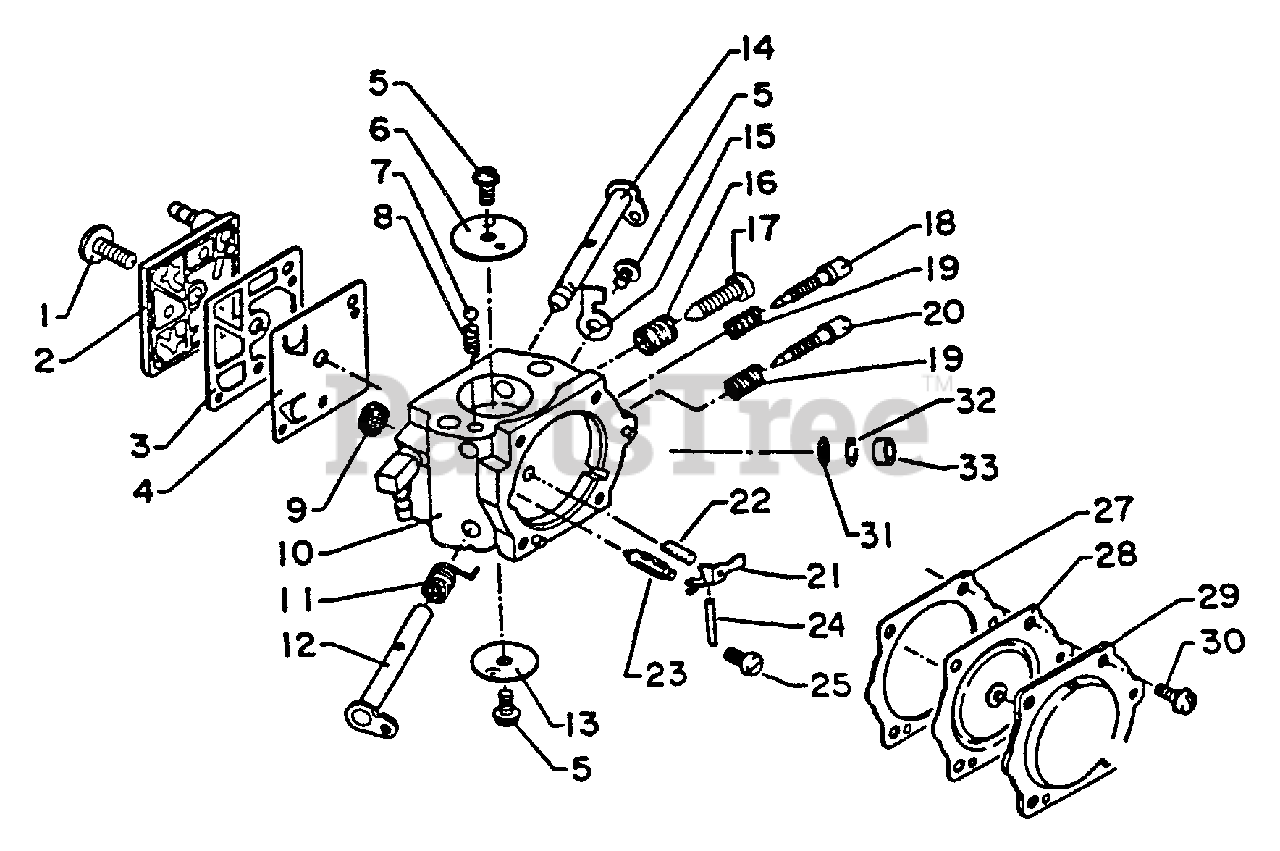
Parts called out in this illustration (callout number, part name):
1	SCREW, PUMP COVER
2	COVER, PUMP
3	GASKET, PUMP
4	DIAPHRAGM, PUMP
6	VALVE, THROTTLE
7	BALL, CHOKE
9	STRAINER
10	BODY, CARBURETOR
11	SPRING, THROTTLE RETURN
12	SHAFT, THROTTLE
13	VALVE, THROTTLE
14	SHAFT, CHOKE
15	STOP, THROTTLE
16	SPRING, IDLE ADJUST
17	SCREW, IDLE ADJUST
18	NEEDLE - LOW SPEED
19	SPRING, IDLE ADJUST
20	NEEDLE - HIGH SPEED
21	LEVER, METERING
22	SPRING, METERING LEVER
23	VALVE, INLET NEEDLE
24	PIN, METERING LEVER
25	SCREW, METERING LEVER PIN
27	GASKET, METERING
28	DIAPHRAGM, METERING
29	COVER, METERING
31	SCREEN, SPARK ARRESTOR
32	RING, RETAINING
33	PLUG, WELCH
